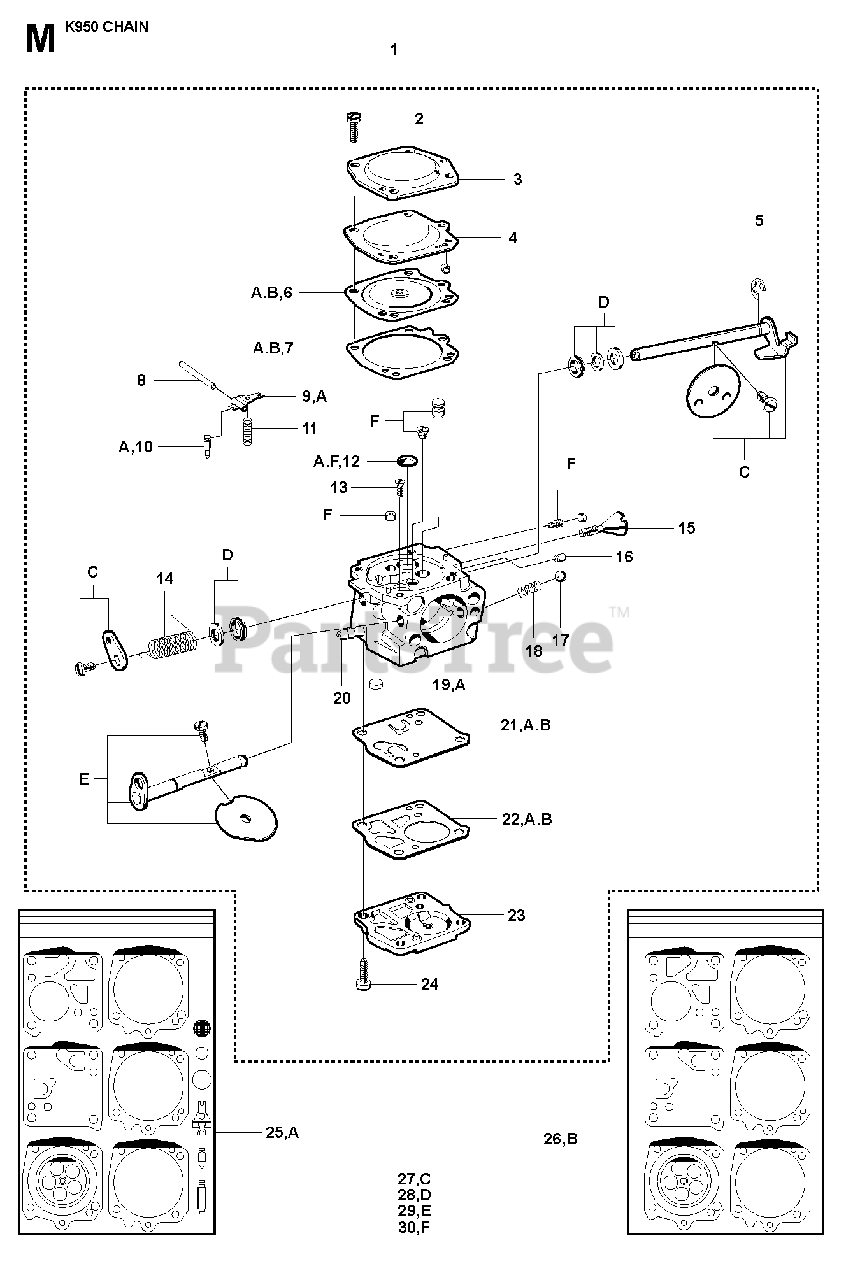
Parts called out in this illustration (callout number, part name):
1	CARBURETTORIncl. 2-24
3	DIAPHRAGM
5	THROTTLE SH."E"RING
8	PIN RETAINING SCREW
13	PIN RETAINING SCREW
15	IDLE SPEED SCREW
16	SPEED SCREW RET BALL
17	CHOKE FRICTION BALL
20	TUBE CONNECTORA
21	FUEL PUMP DIAPHRAMA, B
22	FUEL PUMPA, B
25	REPAIR KITIncl. 6, 7, 9, 11, 12, 20, 21, 22
26	DIAPHRAGMIncl. 6, 7, 21, 22
27	THROTTLE SHAFT(KIT)Kit C
29	CHOKE SHAFT (KIT)Kit E
